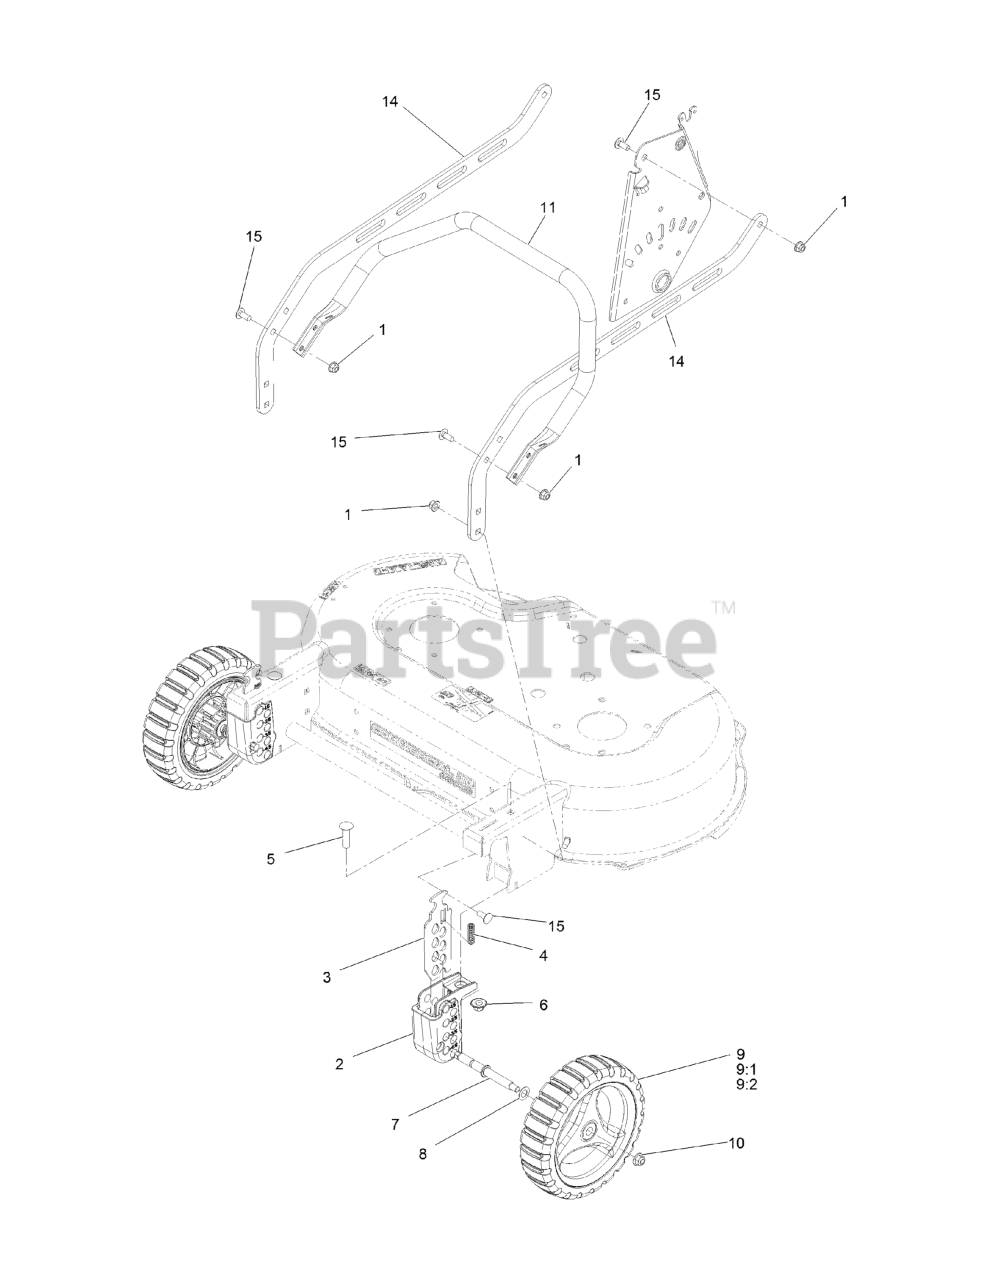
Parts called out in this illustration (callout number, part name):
1	NUT-HF, NI
2	BLOCK-FRONT QUADRANT
3	PLATE, FRONT HEIGHT
4	SPRING-COMPRESSION
5	SCREW-CARR
6	Nut-Nyloc 3/8-16 Flg
7	AXLE-WHEEL
8	WASHER-PLAIN
9	WHEEL ASM, 9" W/BEARINGS
9:1	WHEEL ASM, 9
9:2	BEARING-BALL
10	NUT-HF, NI
11	GUARD-ENGINE
15	SCREW-CARR
